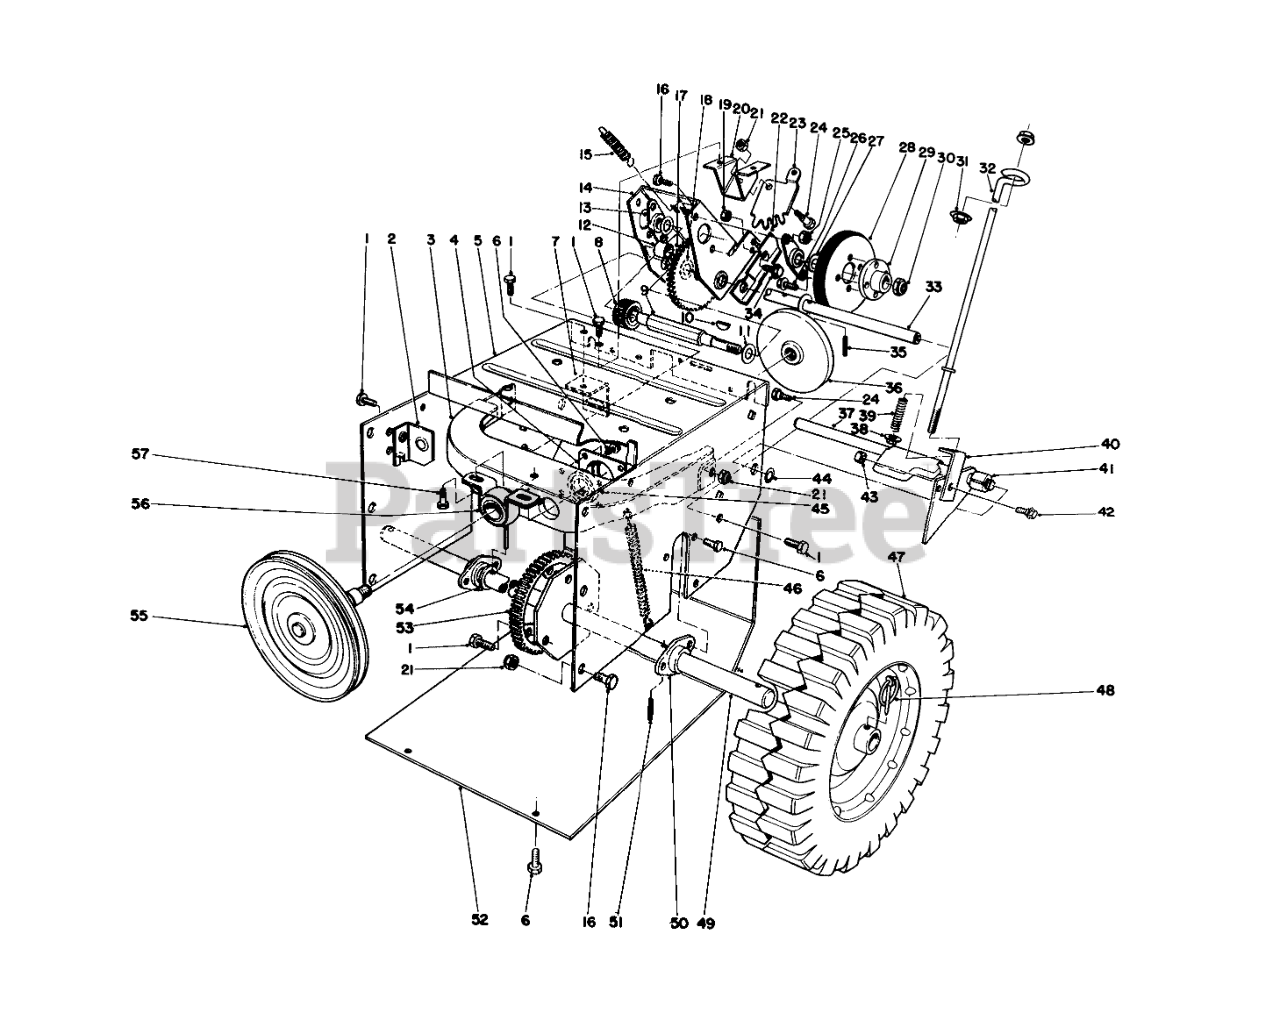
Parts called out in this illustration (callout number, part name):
1	SCREW-HWHTF
2	AUGER CLUTCH MTG FRT
3	"OBS" FRICTION PLT FRAME
4	CUP-BEARING
5	Frame-Traction
6	SCREW-HWH
7	BRACKET-MOUNT, REAR
8	PINION
9	SHAFT-WHEEL, FRICTION
10	KEY-WOODRUFF
11	WASHER-FLAT
12	5/8ID X 1LG BUSHING
13	BEARING-WHEEL, FRICTION
14	BRACKET-SLIDING
15	SPRING-TRACTION
16	SCREW-HH
17	Intermediate Gear & Bushing (Incl. Ref. #12)
18	WASHER-SPECIAL
19	NUT-LOCK, NI
20	MOUNT-LEVER
21	NUT-LOCK, NI
22	CAM-RECEIVER
23	GEAR-QUADRANT
24	BOLT-SHOULDER
25	NUT-LOCK, CONE
26	SCREW-HWHTF
27	WASHER-THRUST
28	WHEEL-FRICTION
29	HUB-WHEEL, FRICTION
30	NUT-LOCK, NI
31	NUT-HF
32	ROD-TRACTION, LOWER
33	SHAFT-PIVOT
34	Screw
35	PIN-SPRING
36	PLATE-FRICTION
37	Traction Engagement Asm.
38	NUT-HHF
39	SPRING
40	BRACKET-TRACTION
41	SPACER
42	SCREW
43	NUT-LOCK, NI
44	RING-RETAINING
45	BEARING-BALL
46	SPRING-PLATE, FRICTION
47	Wheel
48	PIN-LYNCH
49	AXLE SHAFT WA
50	BEARING-AXLE
51	PIN-SPRING
52	Bottom Cover
53	GEAR-AXLE
54	WASHER-THRUST
55	Pulley & Shaft
56	BUSHING ASM
57	SCREW-HWHTF
